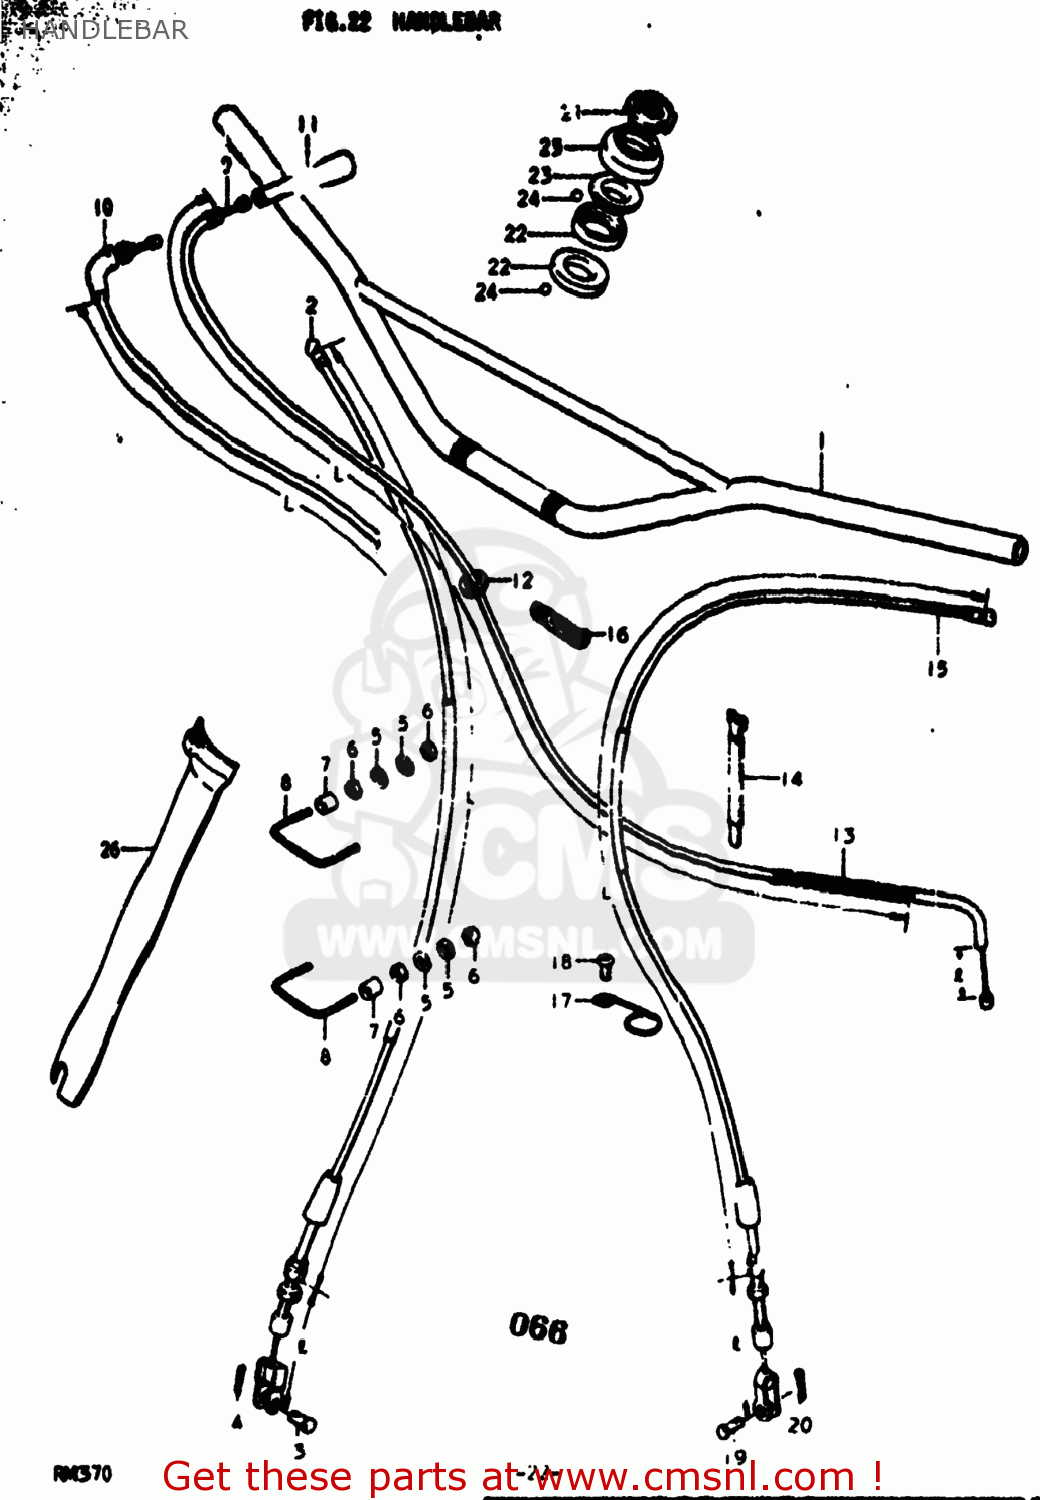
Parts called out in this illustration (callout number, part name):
1	HANDLEBAR
2	CABLE ASSY,FR BRAKE
3	PIN(L:13)
4	PIN
5	WASHER
6	NUT
7	BUSHING
8	CLAMP,CABLE
9	CABLE ASSEMBLY,THROTTLE
10	CABLE ASSEMBLY,THROTTLE
11	SEAL
12	GROMMET
13	PROTECTOR,CABLE
14	CLAMP
15	CABLE ASSEMBLY,CLUTCH
16	CLAMP
17	CLAMP
18	SCREW 6X12
19	PIN(L:13)
20	PIN
21	NUT,STEERING STEM(25X44X10)
22	LACE,STEERING INNER LWR
23	LACE,STEERING OUTER UPR
24	BALL
25	DUST SEAL,STEERING UPR
26	PROTECTOR
